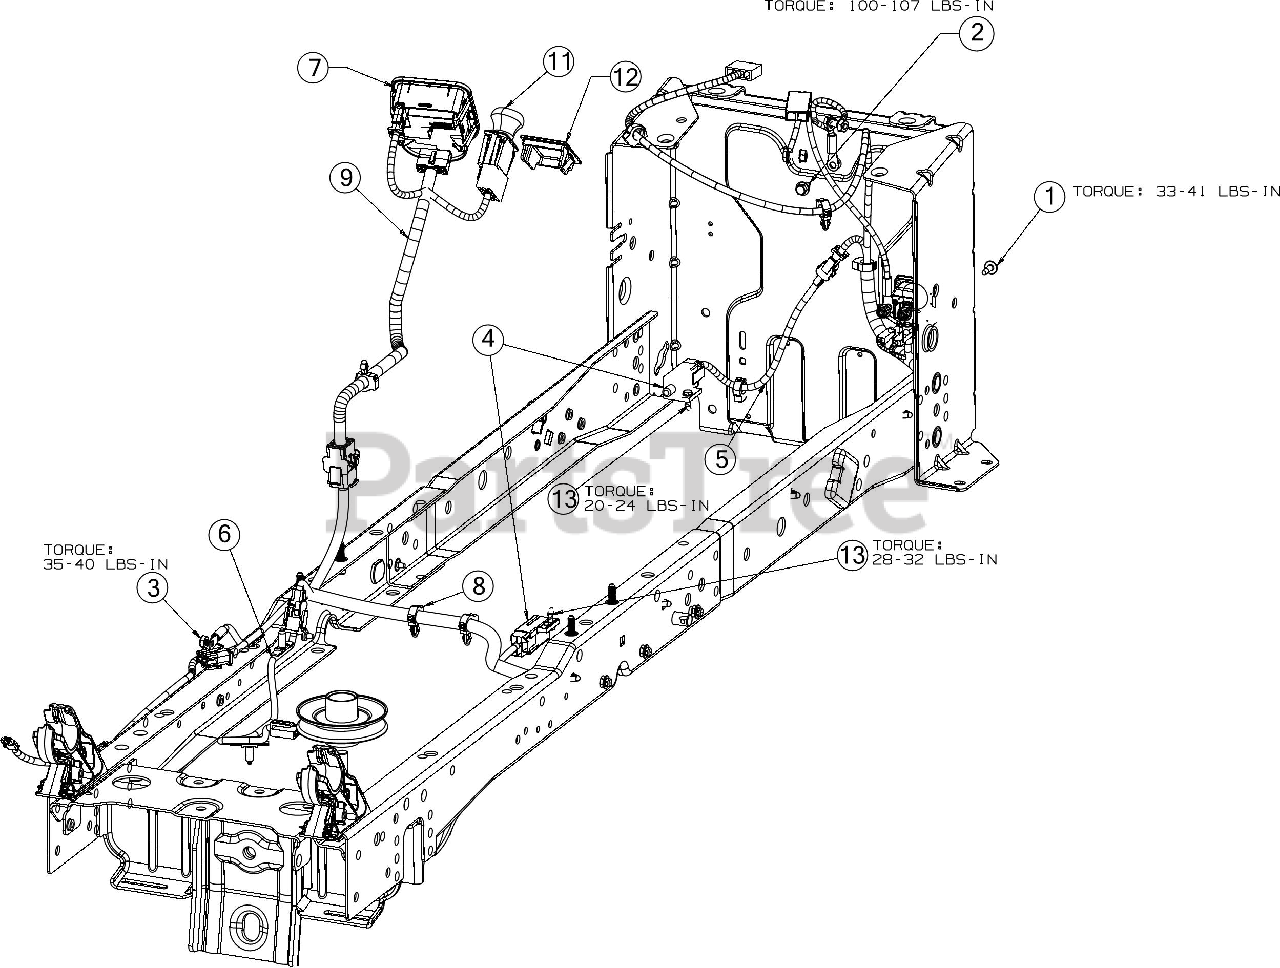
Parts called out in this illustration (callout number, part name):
1	SCREW M6-1 x .625
2	SCREW 1/4-20X.625
3	HEX NUT 1/4-20
4	INTERLOCK SWITCH (NO/NC)
5	REVERSE HARNESS
6	CLUTCH HARNESS 11"
7	MODULE-PBS/HRMTR/SVC MNDR
8	MAIN HARNESS E-PTO/PBS/RMC
9	DASH HARNESS E-PTO/PBS/RMC
11	PTO SWITCH (YELLOW KNOB)
12	DASH HOUR METER PLUG
13	SHOULDER SCREW
